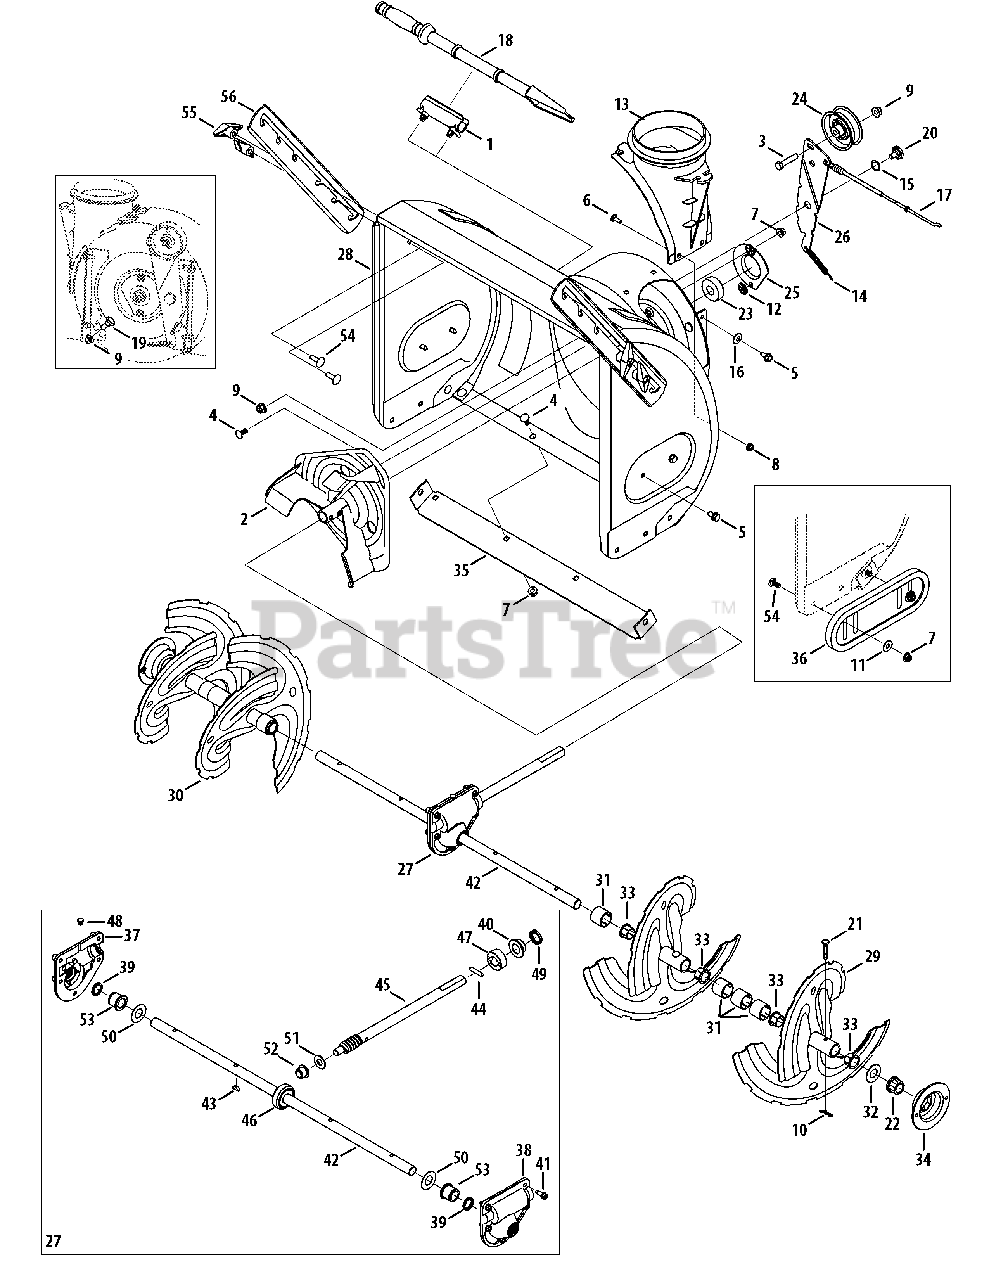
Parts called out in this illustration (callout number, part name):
1	Snow Removal Tool Mount
2	Impeller Assembly, 12" Dia.
3	Hex Screw, 3/8-16, 1.75, Gr5
4	Bolt, Carriage, 5/16-18, .750 Gr1
5	Screw, 5/16-18, 0.750
6	Screw, Carriage, 1/4-20, .750, Gr5
7	Nut, Flange Lock, 5/16-18, Nylon
8	Nut, Flange Lock, 1/4-20, Nylon
9	Nut, Flange Lock, 3/8-16, Nylon
10	Cotter Pin, Bow-tie
11	Washer, Flat, .349 x .879 x .063
12	Nut, Push-on, .25 Dia
13	Chute, Adapter 5" Dia
14	Spring, Extension, .38 OD x 4.59
15	Washer, Wave, .625 x .885 x .015
16	Washer, Bell, .340 x .872 x .060
17	Clutch Cable, Auger, 47.23"
18	Snow Removal Tool
19	Screw, Shoulder, .498 x .34, 3/8-16
20	Screw, Shoulder, .625 x .17, 3/8-16
21	Shear Pin, .25 x 1.50
22	Bearing, Hex Flange x .75 ID
23	Bearing, Ball, .75 ID x 1.85 OD
24	Flat Pulley, Idler, 2.75 OD
25	Housing, Bearing, 1.85 ID
26	Bracket, Auger Idler w/ Brake
27	Gearbox Assembly, Auger, 28"
28	Housing Assembly, Auger 28"
29	Spiral Assembly, LH
30	Spiral Assembly, RH
31	Spacer, 1.25 OD x .75 ID x 1.00
32	Washer, Flat, .76 x 1.49 x .06
33	Bushing, Flange, .80 ID x .91 OD
34	Housing, 1" Hex Bearing
35	Shave Plate, 2.25 x 27.66
36	Slide Shoe
37	Housing, Auger, RH Reduced
38	Housing, Auger, LH Reduced
39	Seal, Oil, .750 x 1.00 x .125
40	Bearing, Flange, .75 x 1.0 x .59
41	Screw, Self-tapping, 1/4-20, 0.750
42	Axle, Auger, 28"
43	Key, Hi-pro 3/16 x 5/8
44	Pin, Dowel, .25 OD x 1.2
45	Shaft, Worm .75 OD
46	Gear, Worm 20T
47	Collar, Thrust
48	Plug, 1/4 x .437
49	Seal, Oil, .75 x 1 x .131
50	Washer, Flat, .760 ID x 1.5 OD
51	Washer, Flat, .51 x 1.12
52	Bearing, Flange, .75 x 1.0 x .925
53	Bearing, Flange, .75 x 1.00 x .975
54	Screw, Carriage, 5/16-18 x 1.00
55	Wing Knob
56	Drift Cutter
